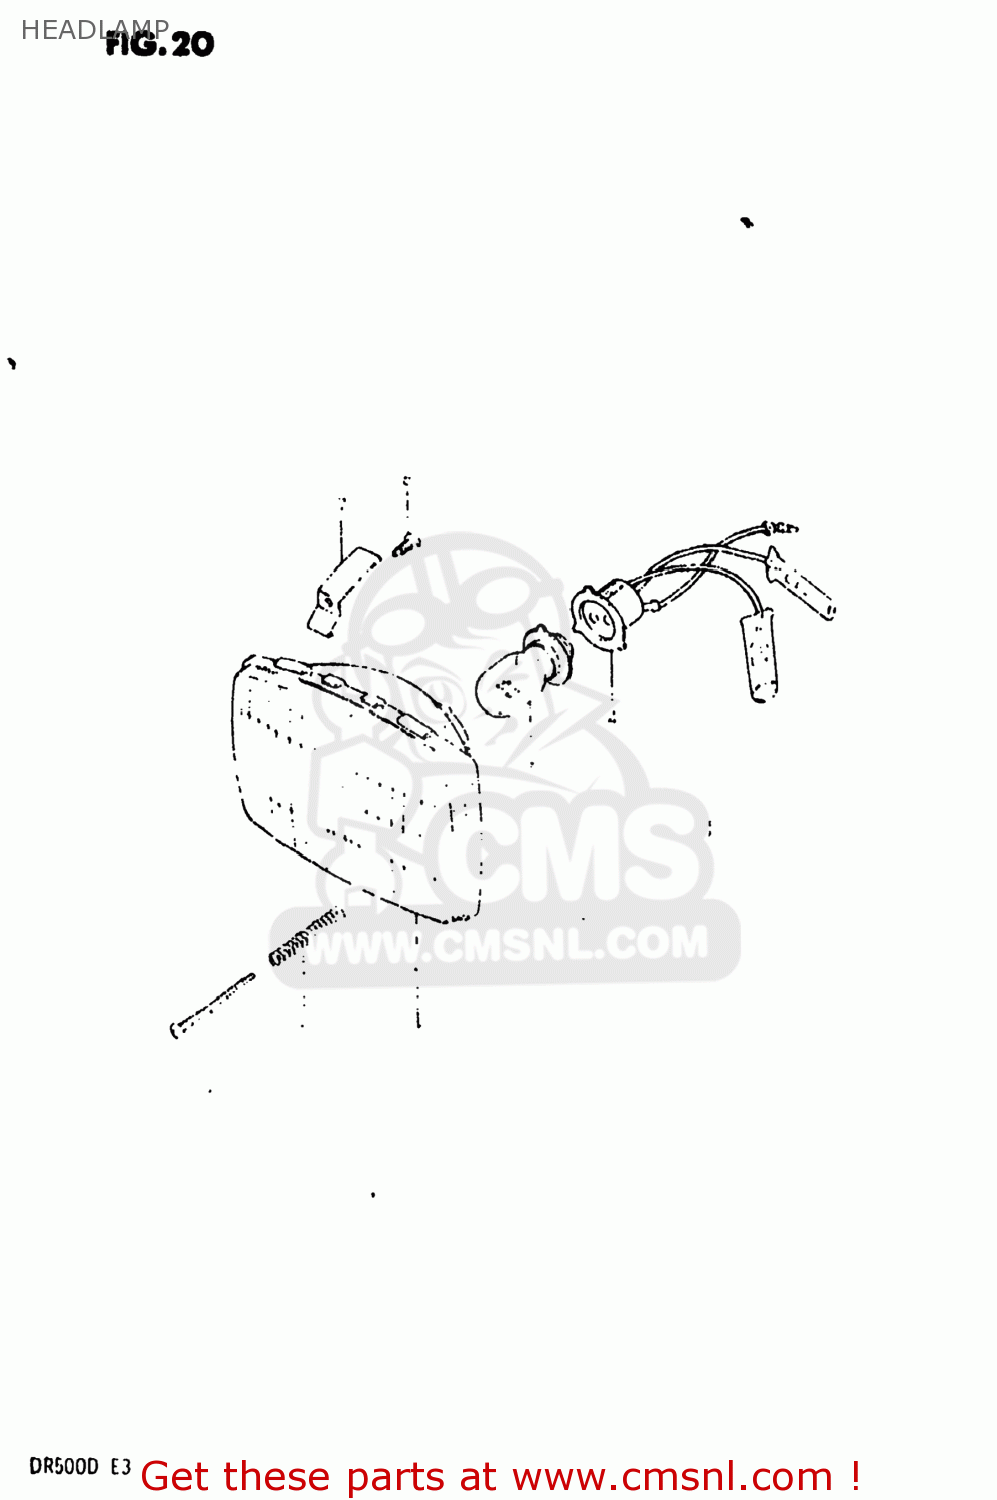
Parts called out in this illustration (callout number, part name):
1	HEADLAMP ASSEMBLY
2	LAMP UNIT
3	BULB(6V15/15W/STANLEY,A3598HA)
4	SOCKET,HEADLAMP
5	SPRING,HEAD LAMP ADJUSTER
6	SCREW,HEADLAMP ADJUST
7	SPRING
8	SPRING,HEADLAMP ADJUST
